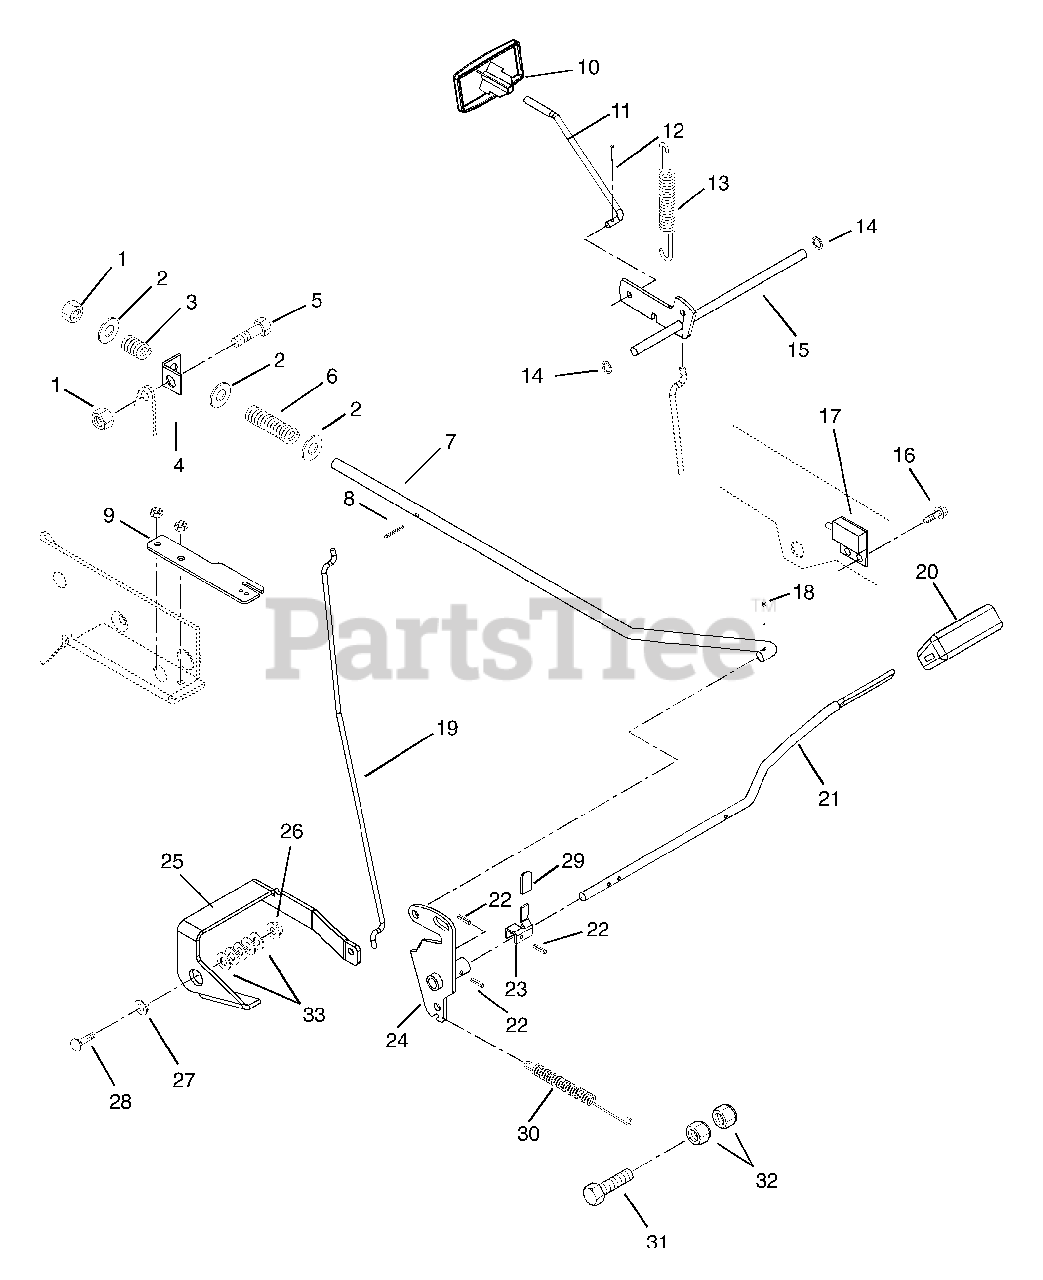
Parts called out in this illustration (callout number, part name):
1	@NUT-LK-CTR .38-16 YWZC
2	@WSHR-FL-STL.406X.812X.065 YWZ
3	SG-COMP .125X.78X1.00 YWZ
4	BRACKET
5	@BLT-HEX .38-16X.75 GR5 YWZC
6	SG-COMP .048X.59X2.06 WLD9
7	ROD - BRAKE
8	PIN-ROLL .125X.75
9	BRAKE GUIDE
10	KNOB, PARK BRAKE
11	ROD, PARKING BRAKE
12	PIN-COTR .06X.50
13	SG-TENS .051X.60X2.25 WLD 7.0
14	RG-RTNG-EXT .250X.010
15	BELLCRANK-PARKING BRAKE
16	@SCR-TAP 12-24X.50 HWH TR YWZC
17	SWITCH- SINGLE POLE N.O.
18	@PIN-CTR .09X.75 EXTPRSQCT YWZ
19	ROD, PARKING BRAKE
20	COVER - PEDAL - BRAKE
21	PEDAL - BRAKE
22	PIN-GRV .188X1.25 TP A
23	LEVER - BRAKE SWITCH
24	ARM + HUB - BRAKE
25	LEVER, PARKING BRAKE
26	@NUT-LK-CTR .31-18 YWZC
27	BSHG, FLG .325X.499X.26X.88
28	BLT-RDHDSQSHK.31-18X.75 GR2 YW
29	GRIP .062 X .375 X 1.000 RE
30	SG-TENS .105X.85X5.00 WLD 40
31	BLT .50-13X2.75 DHCS
32	NUT-LK-JAM-NYL .75-10 YWZC
33	WSHR-PLASTIC .390X.875X.062
